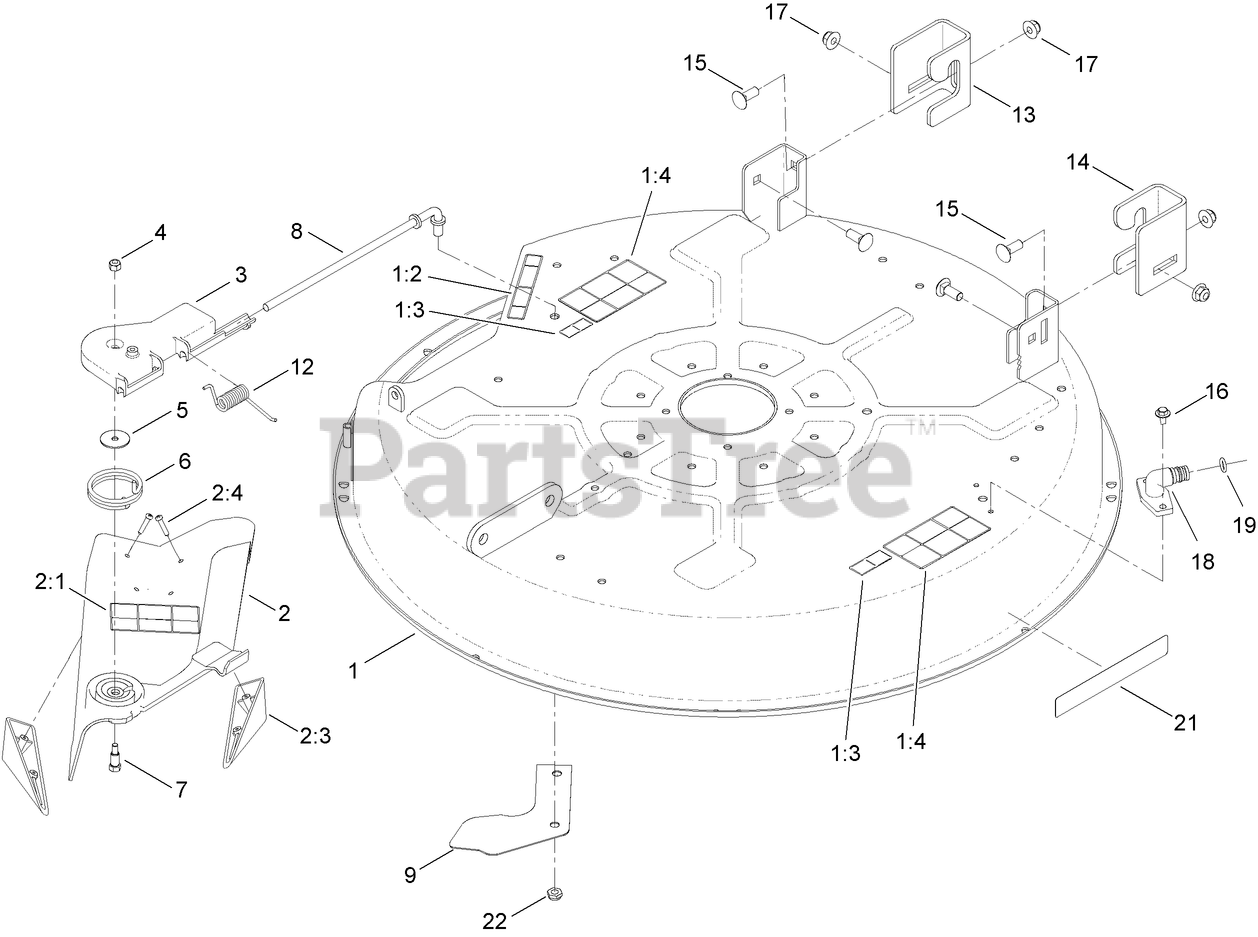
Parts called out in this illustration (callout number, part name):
1	32 INCH DECK AND DECAL ASM
1:2	DECAL-DANGER
1:3	DECAL-DANGER
1:4	DECAL-DANGER
2	32 INCH DEFLECTOR ASM
2:1	DECAL-DANGER
2:3	KICKER
2:4	SCREW-PPH
3	PIVOT-HINGE, DEFLECTOR
4	NUT-LOCK, NI
6	SPRING-TORSION
7	BOLT-SHOULDER
8	ROD-PIVOT
9	RAMP-DEFLECTOR
12	SPRING-TORSION
14	BRACKET-HANGER, LH
15	BOLT-CARR
16	SCREW-HHFTF
17	NUT-HF, NI
19	O-RING
21	DECAL-RECYCLER
